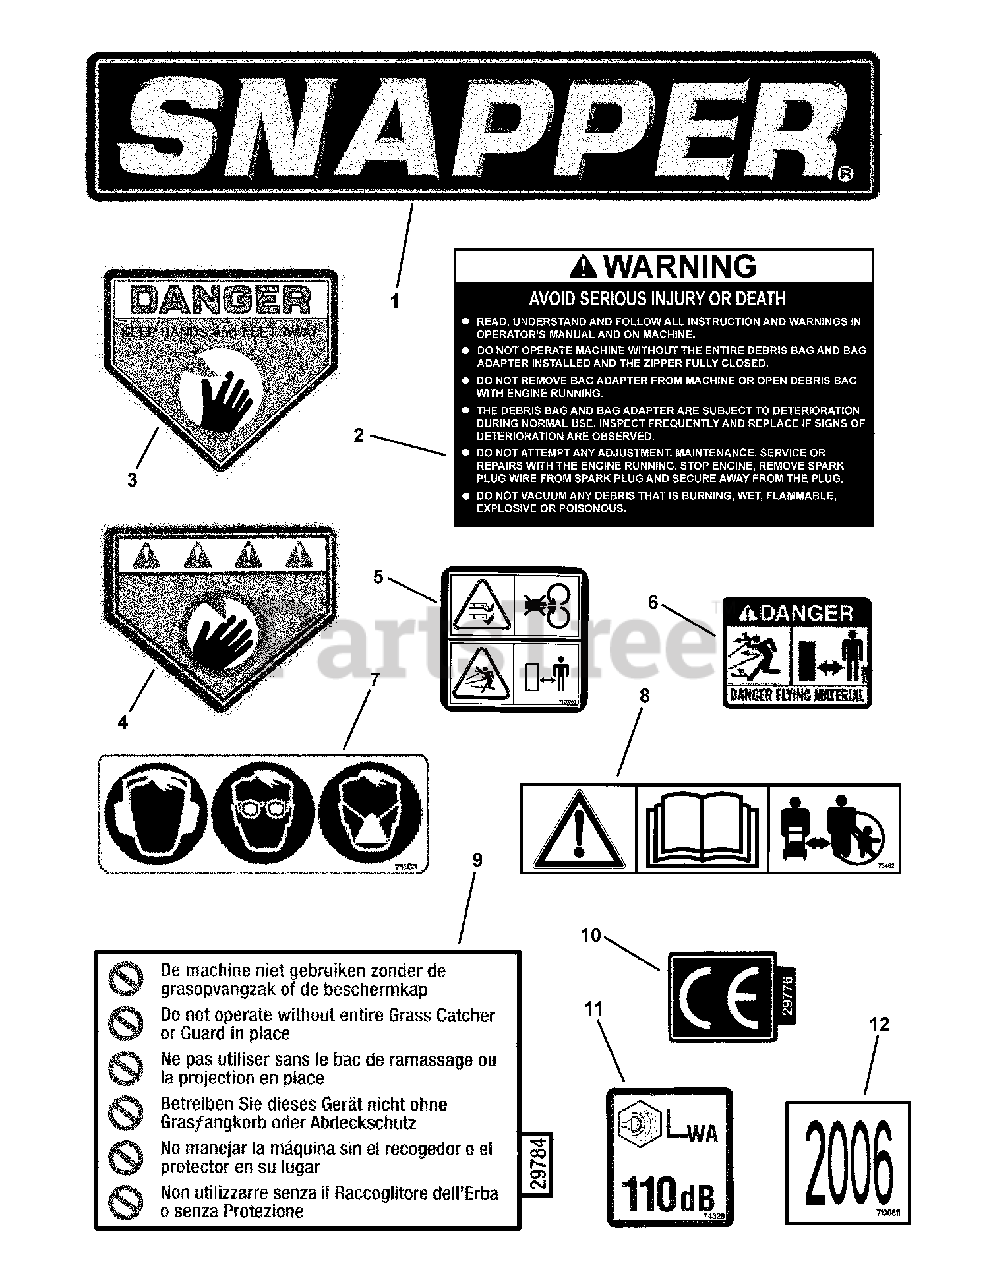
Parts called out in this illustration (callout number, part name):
1	DECAL, SNAPPER
2	DECAL, Warning, Vacuum
3	DECAL, Danger, Cut Finger
4	DECAL, WARNING
5	DECAL, Deck Symbols International
6	DECAL, Thrown Objects
7	DECAL, Personal Protection
8	DECAL, Caution Symbols
9	DECAL, DK/Chute INT'L Warning
10	DECAL, Euro Community (CE)
11	DECAL, SOUND 110
12	DECAL, 2006 Year of Manufacture (shown)
